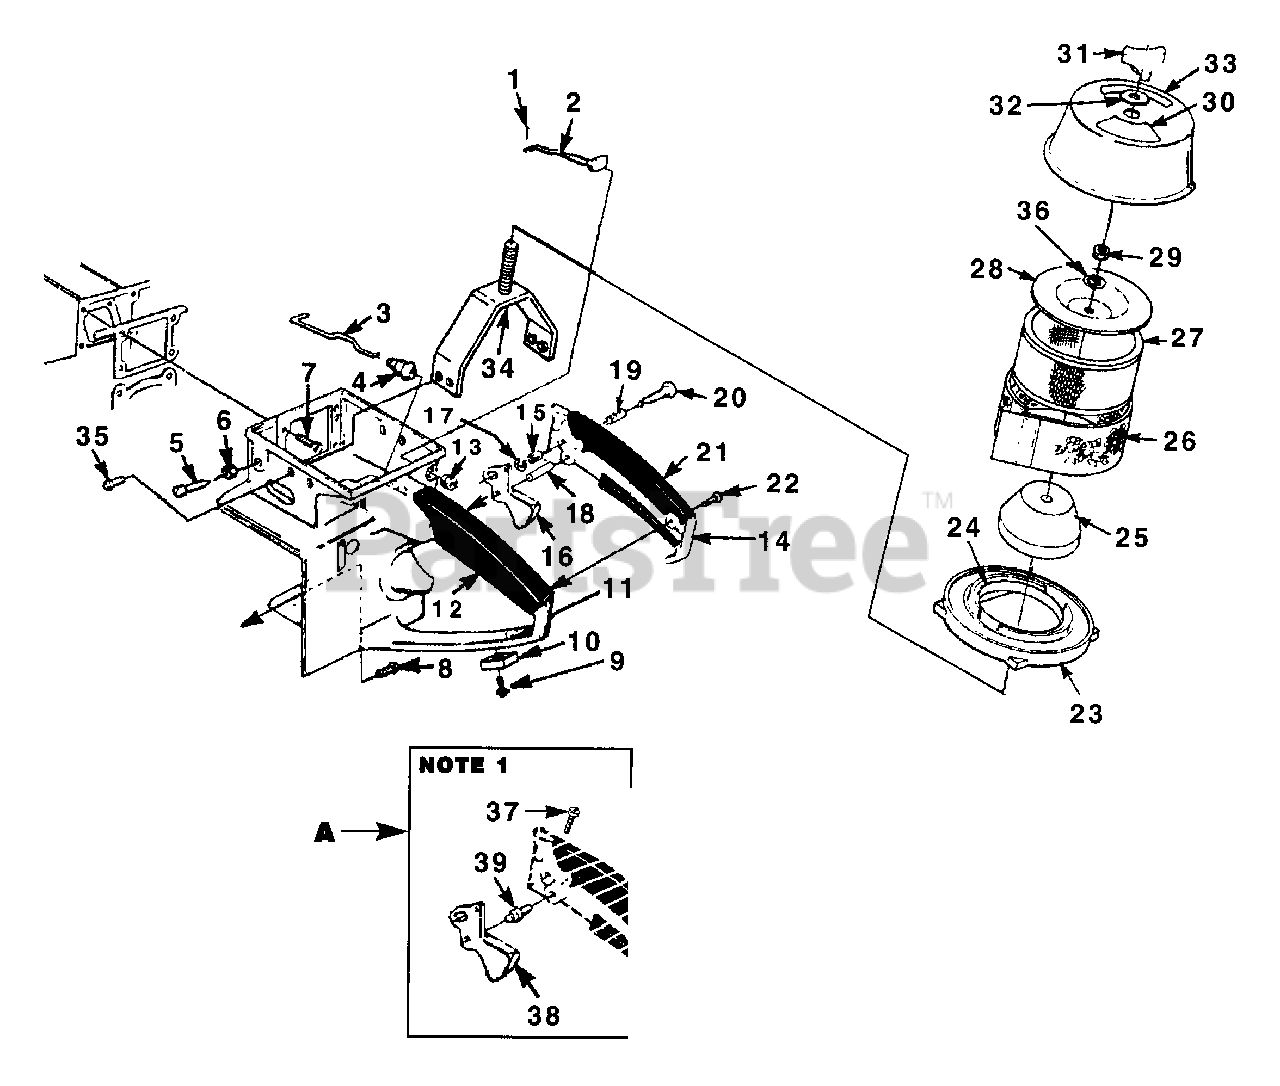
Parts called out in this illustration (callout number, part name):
1	COTTER PIN
2	CHOKE ROD
3	ROD - Throttle
4	BOOT - Throttle Rod
5	SCREW - Idle Adjustment
6	NUT - Jam (5/16-24)
7	SCREW - Hex hd (12-24 X 5/8")
8	SCREW - Hex hd (12-24 X 7/8")
9	SCREW - (10-24 X 1/2")
10	PAD - Wear
11	HANDLE - Throttle
12	GRIP - Throttle Handle
13	GROMMET
14	COVER - Throttle Handle
15	BUSHING
16	TRIGGER
17	RING - Retaining
18	PIN - Trigger
19	SPRING - Throttle lock
20	PIN - Throttle
21	GRIP - Throttle Handle
22	SCREW - Pan hd (8-32 X 1/2")
23	RING & GASKET ASSY
25	FILTER - Air
26	PRE FILTER - Felt
27	ELEMENT - Air Filter
28	COVER - Filter Element
29	NUT - Hex (5/16-18)
30	DECAL - Warning
31	KNOB - Handle
32	GASKET
33	DECAL - Instruction
34	BRACKET - Cover
37	SCREW - (8-32 X 5/8")
38	TRIGGER
